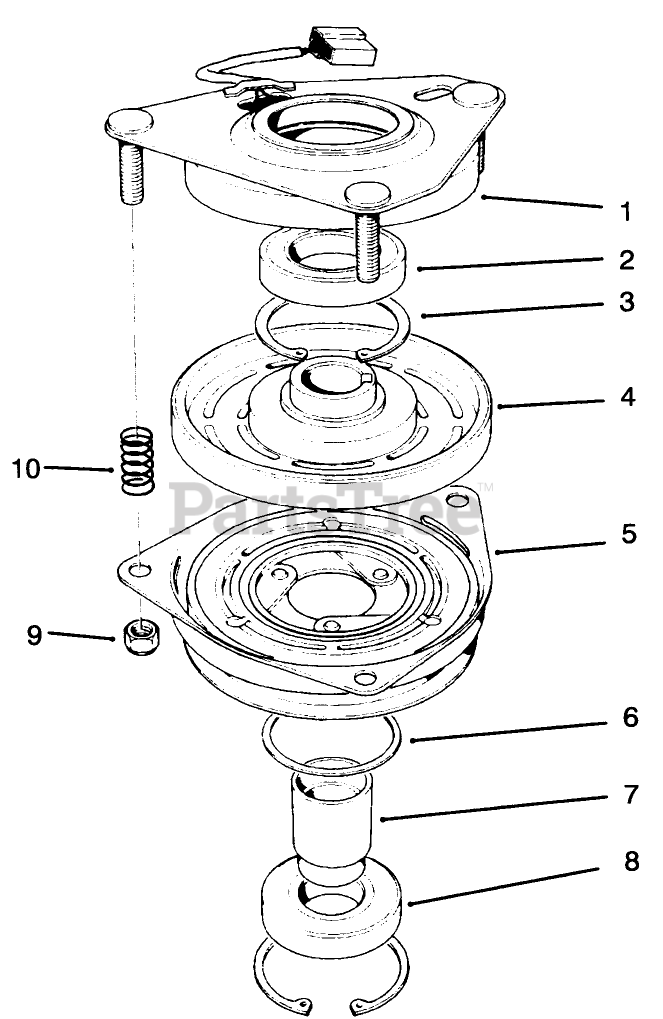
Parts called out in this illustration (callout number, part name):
1	FIELD BEARING ASM
2	BEARING-FIELD
3	RING-RETAINING
4	FIELD COIL/ROTOR BEARING ASM
6	SPACER-BEARING, PULLEY
7	COLLAR-BEARING
9	NUT-HEX
10	SPRING
